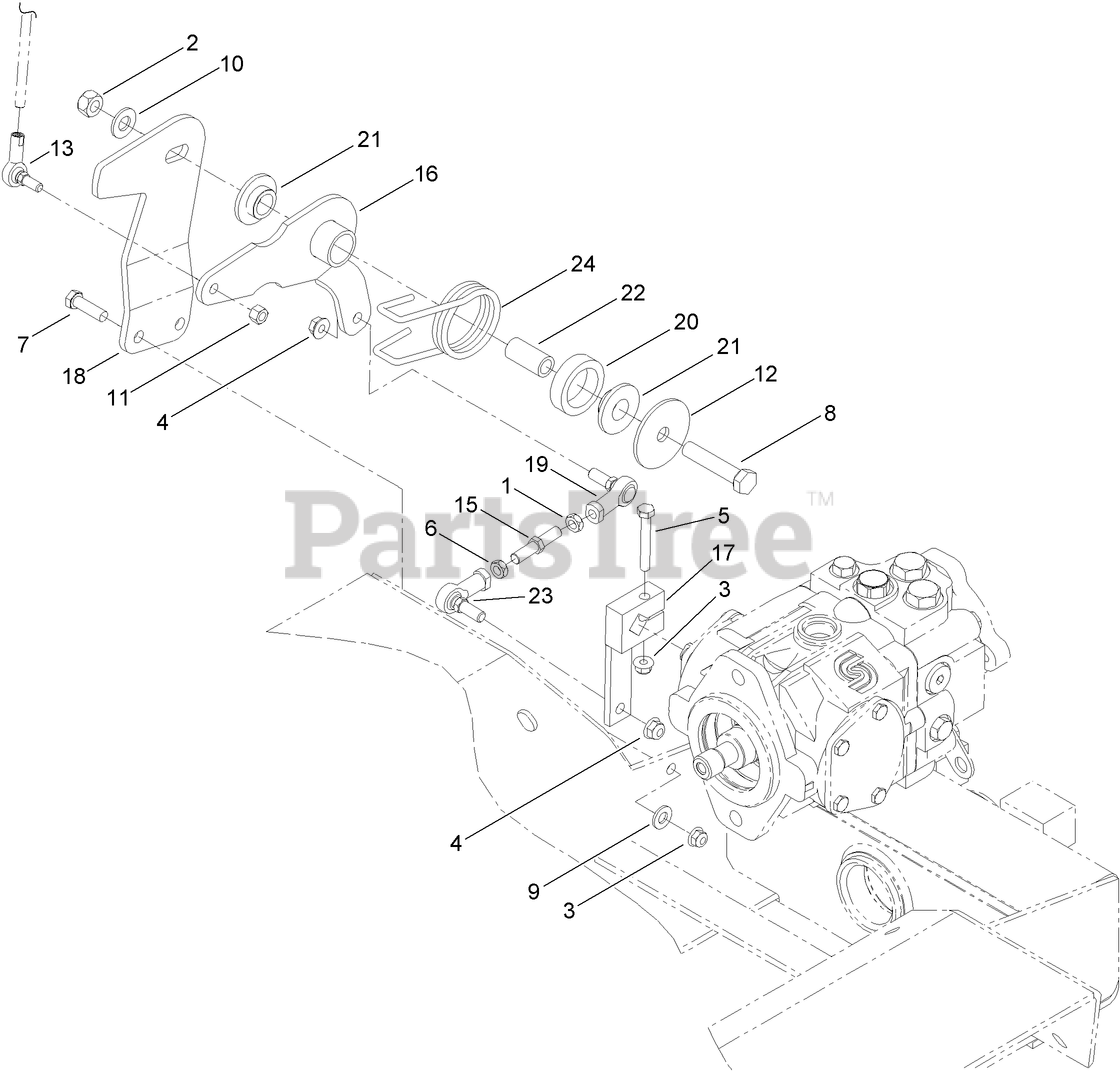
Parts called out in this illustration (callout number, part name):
1	NUT-JAM, LH
2	NUT-LOCK, HEX
3	NUT-HF, NI
4	NUT-HF, NI
5	SCREW-HH
6	NUT-JAM, HEX
7	BOLT
8	SCREW-HH
9	WASHER-FLAT
10	WASHER-FLAT
11	NUT-HEX
12	WASHER-FLAT (SPECIAL)
13	JOINT-BALL, LH (FEMALE)
15	SCREW-JACK, CONTROL
16	PIVOT-CENTERING
17	LEVER-CONTROL, PUMP
18	PLATE-CENTERING
19	JOINT-BALL, STUD (ROD END)
20	SPACER-COLLAR
21	BUSHING-INSERT, PLASTIC
23	JOINT-BALL
